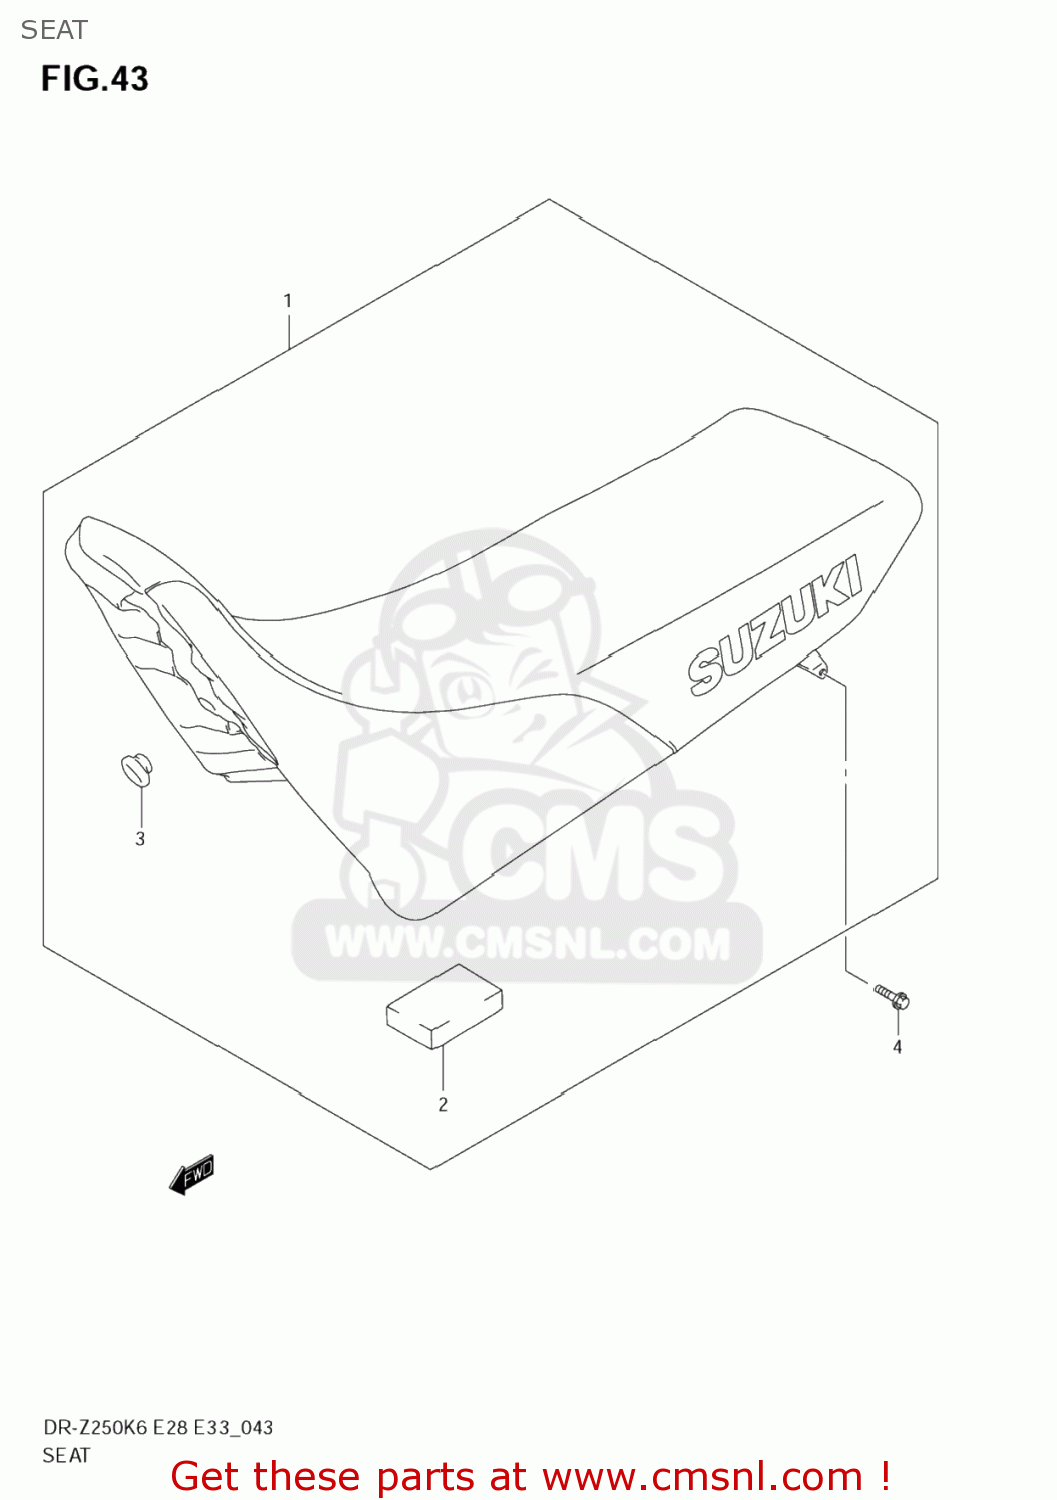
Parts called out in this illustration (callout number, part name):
1	SEAT ASSY
2	CUSHION
3	CUSHION
4	BOLT
